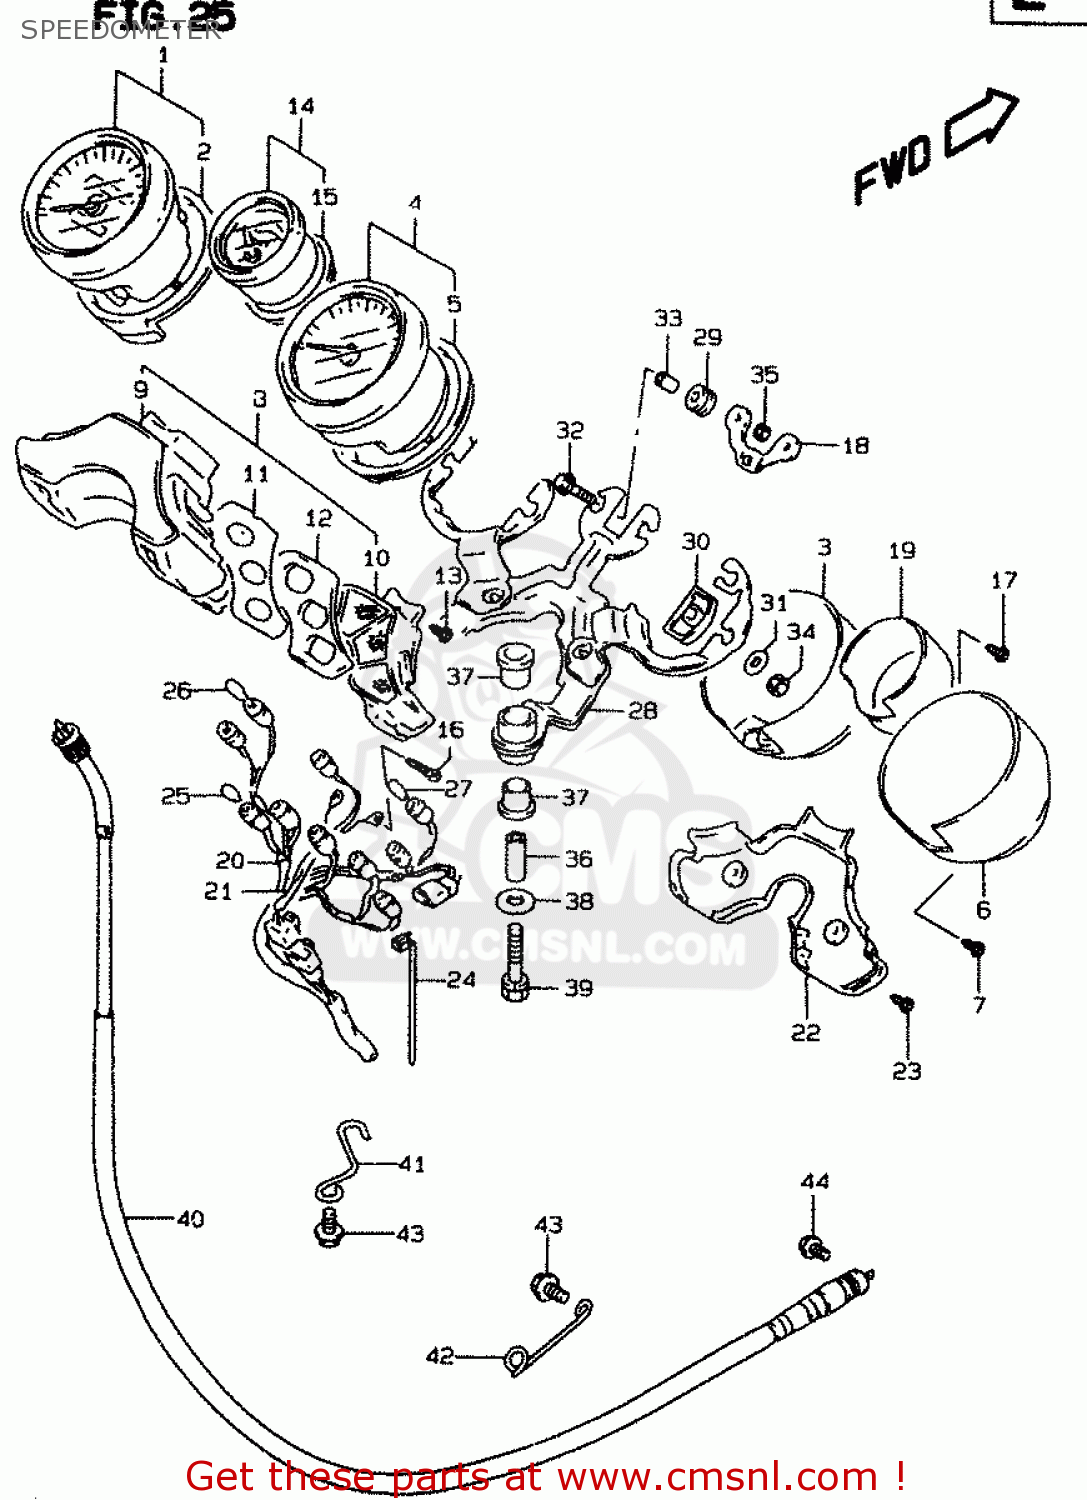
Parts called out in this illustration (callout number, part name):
1	SPEEDOMETER
2	DAMPER
3	COVER,SPEEDOMETER
4	TACHOMETER
5	DAMPER
6	COVER,TACHOMETER
7	SCREW
8	BOX,PILOT
9	CASE,UPR
10	LWR CASE
11	PANEL
12	GASKET
13	SCREW
14	FUEL,METER
15	DAMPER
16	SCREW(3X22)
17	SCREW
18	PLATE,SET
19	COVER,FUEL METER
20	SOCKET,METER
21	SOCKET,FUEL METER
22	COVER,PILOT BOX
23	SCREW
24	CLAMP
25	BULB(12V3W,T6.5)
26	BULB(12V1.7W,T6.5)
27	BULB(12V1.7W,T10,WB121)
28	BRACKET,METER
29	DAMPER
30	DAMPER
31	WASHER(5.2X16X1)
32	WASHER,FUEL,METER
33	SPACER,FUEL METER
34	NUT
35	NUT
36	BUSH(L:31)
37	CUSHION
38	WASHER (8.5X26X1.6)
39	BOLT
40	CABLE ASSY,SPEEDOMETER
41	GUIDE,SPEEDOMETER CABLE NO.1
42	GUIDE,SPEEDOMETER CABLE NO.3
43	BOLT
44	SCREW
